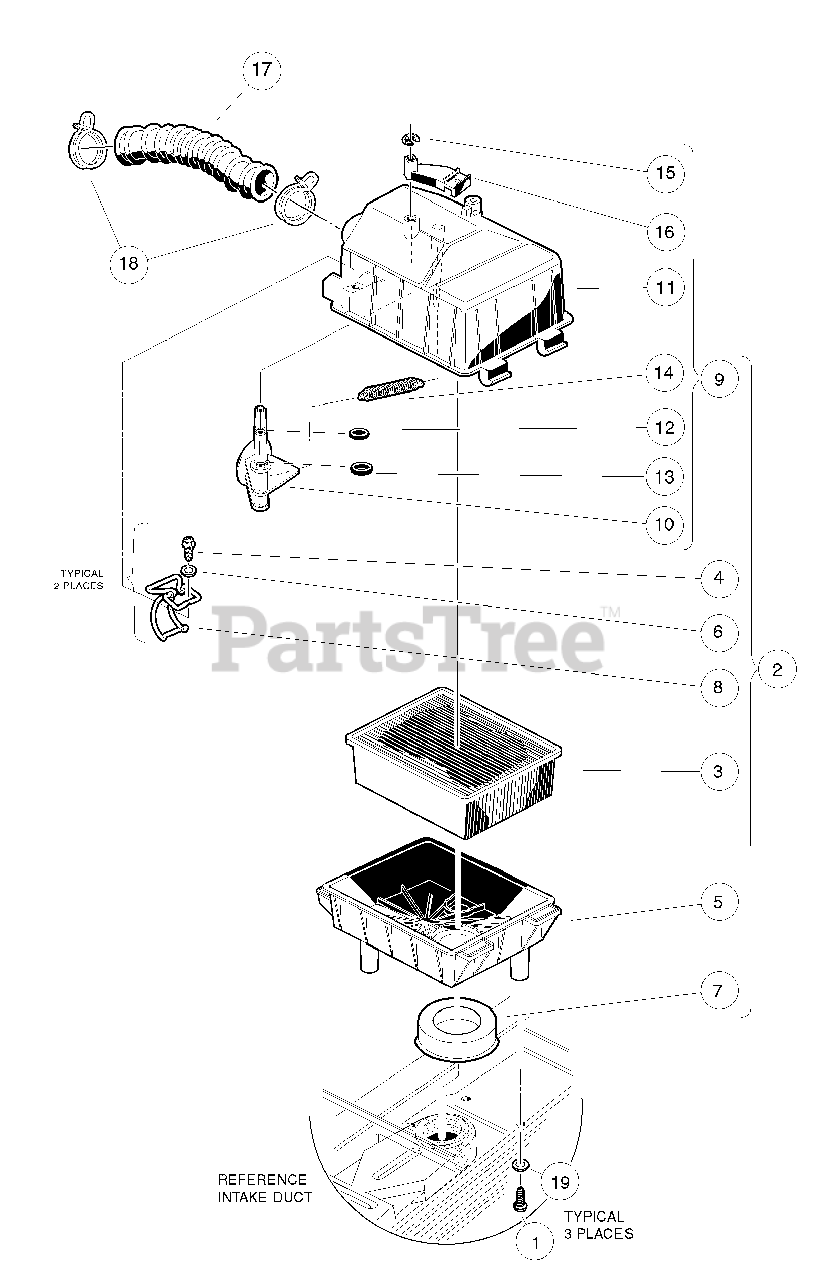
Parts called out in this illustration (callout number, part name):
1	Screw, #12-16 X 0.625 Hi-Lo
2	Assembly, Air Box
3	Filter, Air
4	Screw, #8 X 0.500, Hex-Head Hi-Lo
5	Bottom, Air Box
6	Washer, #8 Stainless-Steel Flat
7	Seal, Intake
8	Latch, Wireform
9	Top Assy, Air Box
10	Valve, Choke
11	Top, Air Box
14	Spring, Extension Return
15	Retaining Ring 0.25, Shaft
16	Lever, Choke
17	Hose, Air Intake
18	Clamp, 1.58" ID Hose
19	Washer, 1/4 Type A Narrow Flat
